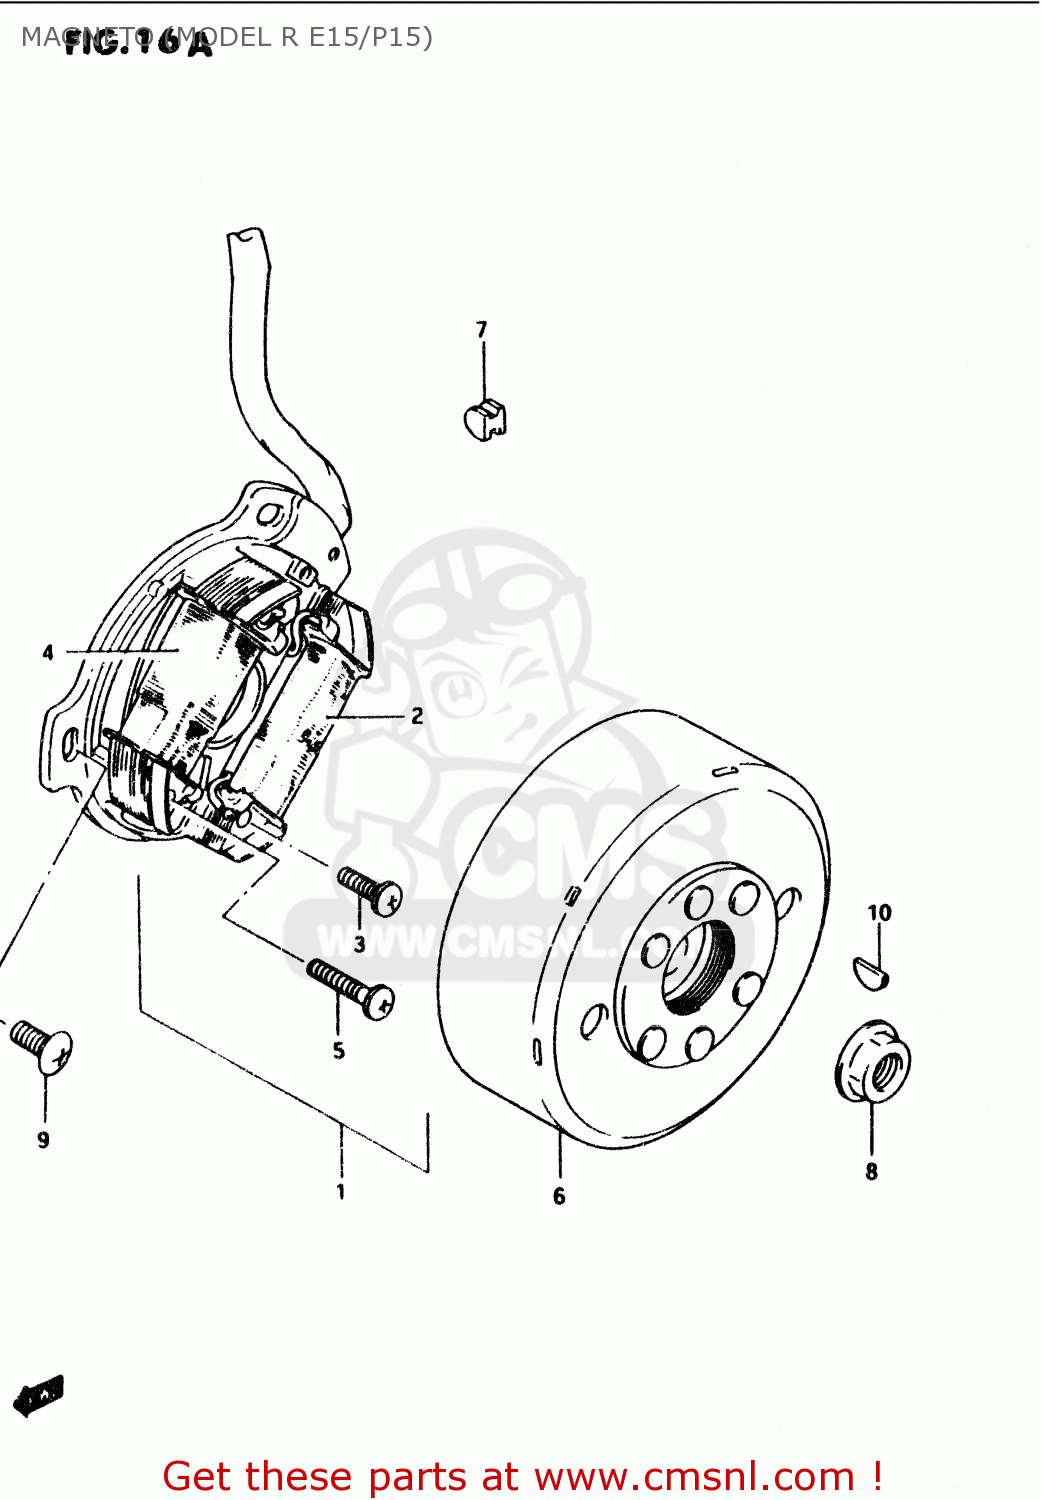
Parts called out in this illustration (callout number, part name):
1	STATOR ASSY
2	COIL,PRIMARY
3	SCREW
4	COIL, LIGHTING
5	SCREW
6	ROTOR, FLYWHEEL
7	PLUG
8	NUT
9	SCREW 5X12
10	KEY
